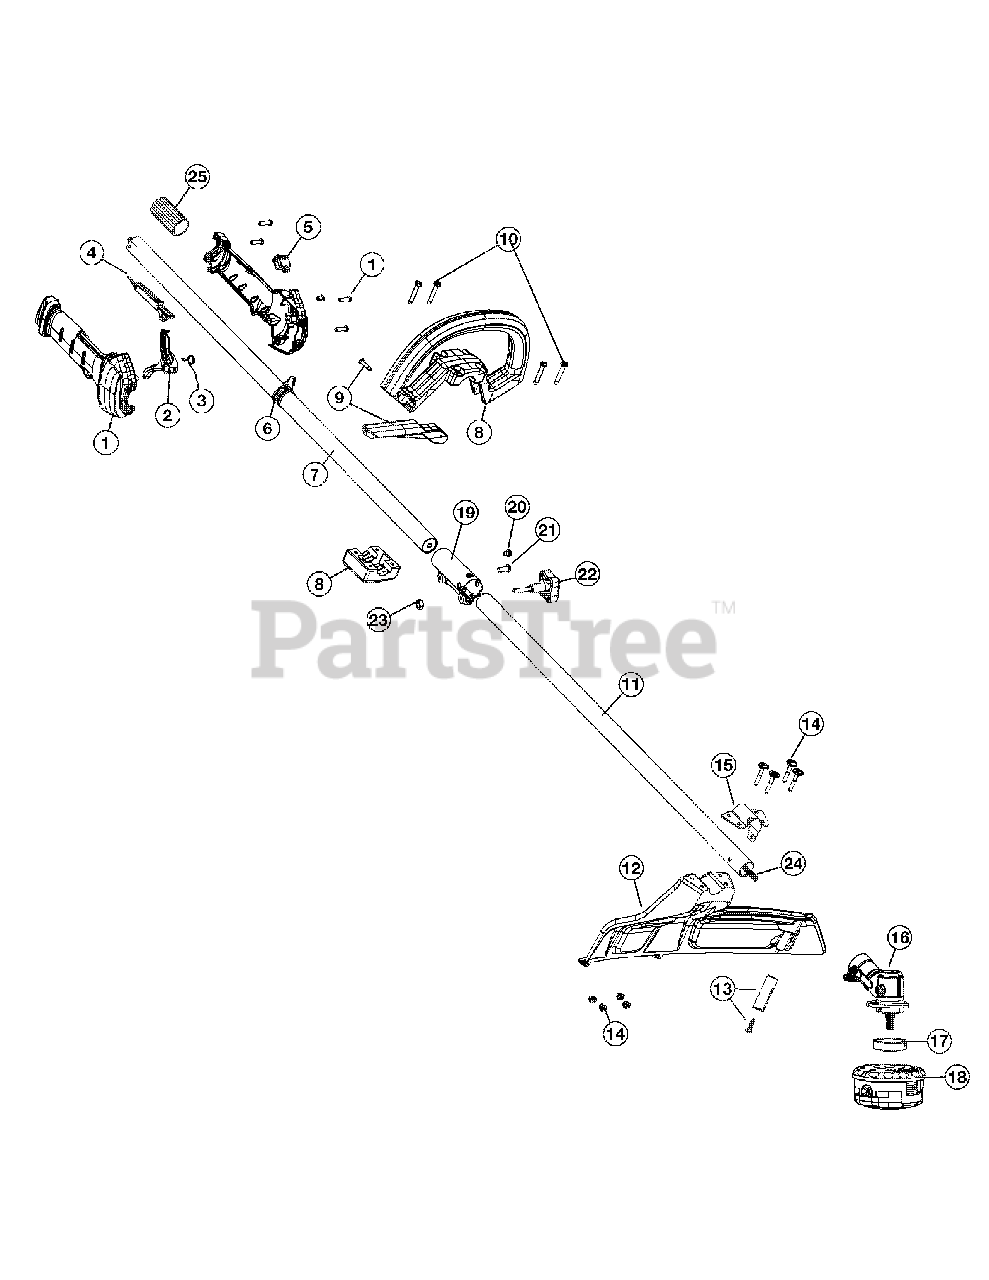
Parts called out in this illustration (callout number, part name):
1	Throttle Housing Assembly
2	Throttle Trigger
4	Throttle Lock-out
6	Shoulder Strap Clip
7	Upper Drive Shaft Housing Assembly
8	D-Handle Assembly
9	Barrier Bar Assembly
11	Lower Drive Shaft Housing Assembly
12	Shield Assembly
13	Blade Assembly
15	Guard Mounting Bracket
17	Gearbox Spacer
18	Cutting Head Assemly
19	Split Boom Coupler
22	Adjustment Knob
23	Knob Retaining Nut
24	Lower Flexible Drive Shaft
25	Grip Spacer
